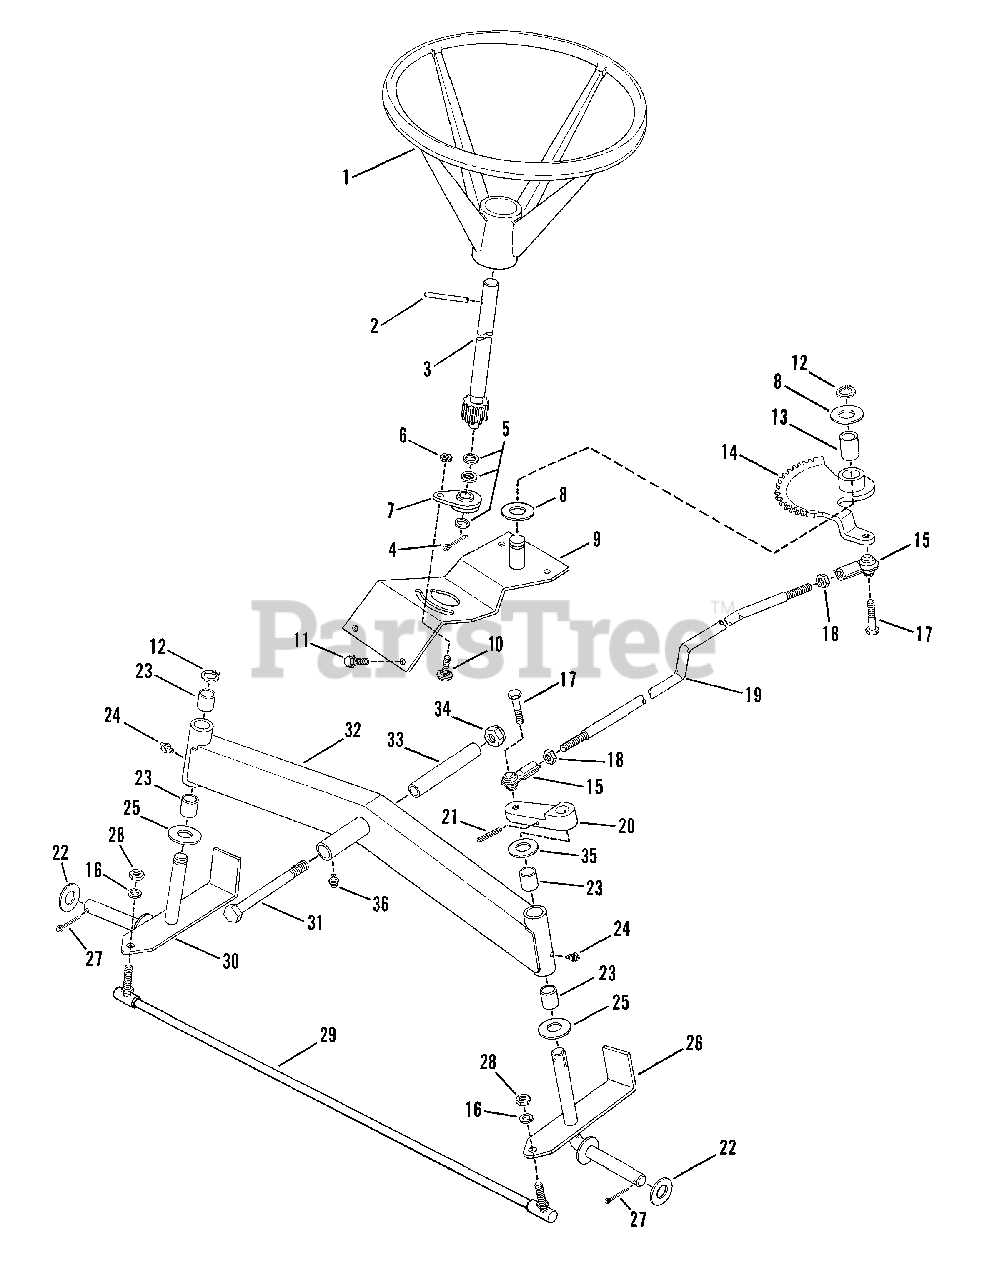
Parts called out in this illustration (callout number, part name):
1	STEERING WHEEL
2	ROLL-PIN
3	SHAFT, Steering
4	PIN, Cotter 3/32 x 1"
5	WASHER, Shim
6	LOCKNUT, 1/4-20 Hex Flange
7	ADJUSTER, Steering
8	WASHER, Thrust
9	ASSEMBLY, Steering Support
10	BOLT, 1/4-20 x 5/8" Short Neck Carriage
11	SCREW, 5/16-18 x 5/8" Self-Tapping
12	RING, Retaining
13	BEARING
14	ASSEMBLY, Sector
15	BALL JOINT, Drag Link 3/8-24
16	LOCKWASHER, 3/8 Split
17	SCREW, 3/8-24 x 1-1/4" Hex Head Cap
18	JAM-NUT, 3/8-24 Hex
19	DRAG-LINK
20	ARM, Steering
21	ROLL-PIN
22	WASHER, Flat
23	BEARING, Sleeve
24	LUBE FITTING, Straight (press-fit for .187 dia. Hole)
25	WASHER, Thrust
26	SPINDLE ASSEMBLY, L.H.
27	COTTER-PIN
28	NUT, 3/8-24 Hex
29	TIE-ROD
30	SPINDLE ASSEMBLY, R.H.
31	SCREW, 1/2-20 x 4-1/2" Hex Head Cap
32	ASSEMBLY, Front Axle
33	SPACER, Axle Pivot
34	LOCKNUT, 1/2-20 Hex
35	WASHER
36	FITTING, Lube
